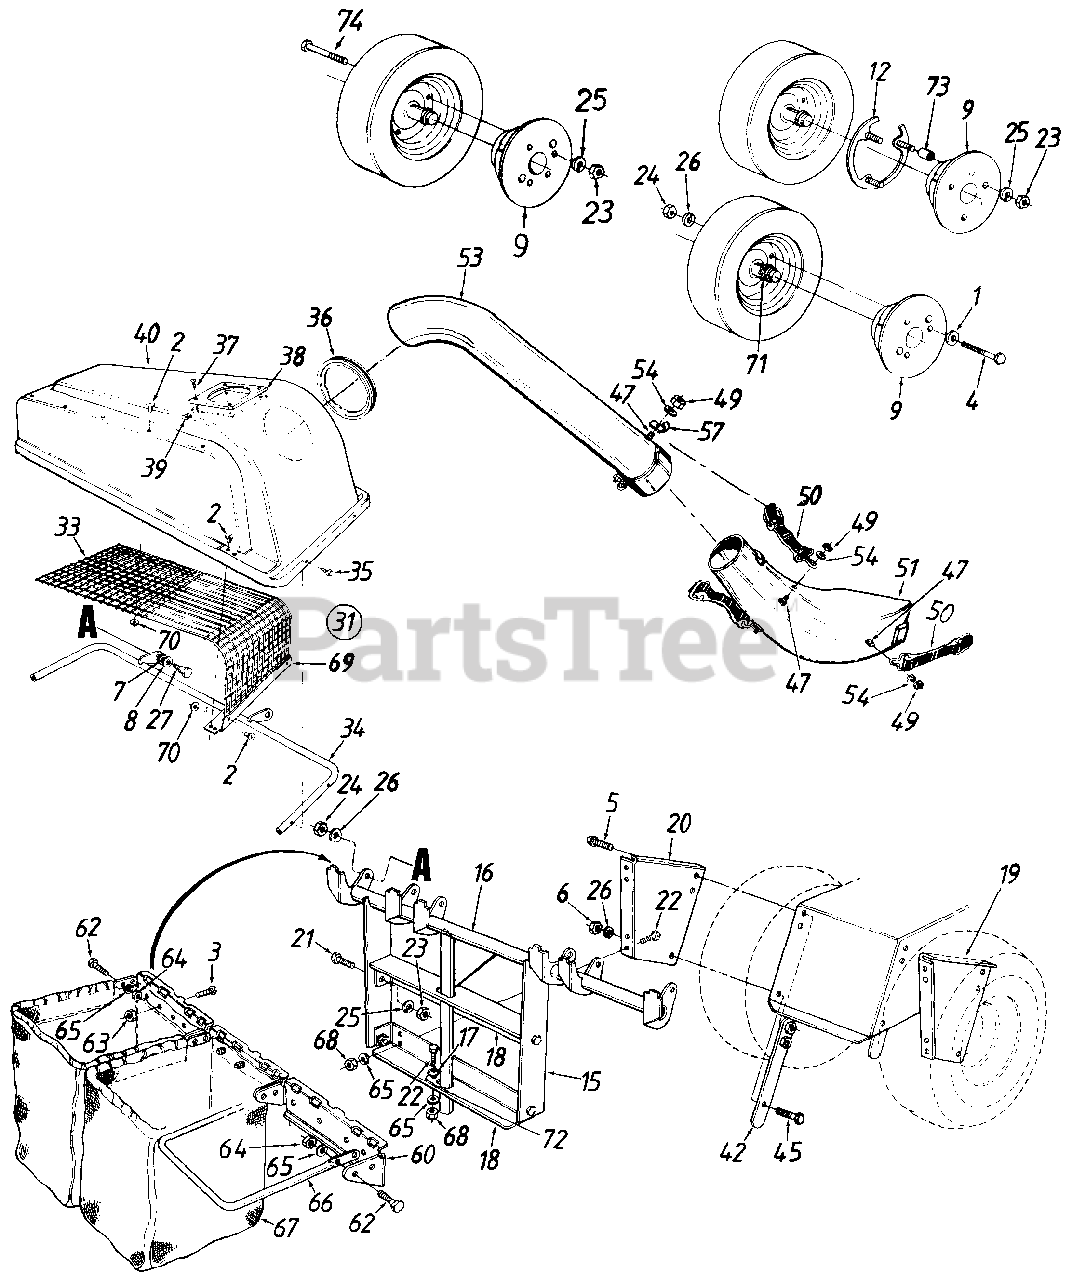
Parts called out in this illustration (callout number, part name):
1	Fl-Wash. .385" I.D.
2	Pop Rivet
3	Truss Mach. Scr. 010-24 x 38" Lg.
4	Hex Bolt 3/8-16 x 4.5" Lg.
5	Hex Wash. Hd. Tap Scr. 5/16-18 x .62"
6	Hex Nut 3/8-24 Thd.
7	Bell-Wash. .515" I.D.
8	Fl-Wash. .510" I.D.
15	Catcher Support Tube Mtg. Brkt.
18	Catcher Latch and Support Brkt.
22	Hex Bolt 1/4-20 x .62" Lg.- Grade 5
23	Hex Nut 5/16-18 Thd.
24	Hex Nut 3/8-16 Thd.
25	L-Wash. 5/16" I.D.
26	L-Wash. 3/8" I.D.
27	Shld. Bolt 3/8-16 x .500" Dia.
31	Grass Catcher Cover Ass'y. Comp.
33	Screen
36	Tube Seal
37	Truss Mach. 8-Tap Scr. #10 x .5" Lg.
38	Plastic Plate
39	Speed Nut
40	Grass Catcher Cover
47	Hex Bolt 1/4-20 x .50" Lg.
49	Hex Ins. L-Nut 1/4-20 Thd.
50	Retainer Strap Ass'y.
51	Discharge Chute
53	Catcher Elbow Tube
54	L-Wash. .270" I.D. x .57" O.D.
57	Retainer Hook Brkt.
62	Hex Bolt 1/4-28 x .75" Lg.
63	Hex Sems Nut 010-24 Thd.
64	Hex Nut 1/4-28 Thd.
65	L-Wash. 1/4" I.D.
66	Catcher Bag Frame
67	Grass Catcher Bag
68	Hex Nut 1/4-20 Thd.
71	Foam Strip 1-1/8" x 1-1/2" x 3/8"
73	Spacer
74	Flex Bolt 5/16-18 x 4" Lg.
